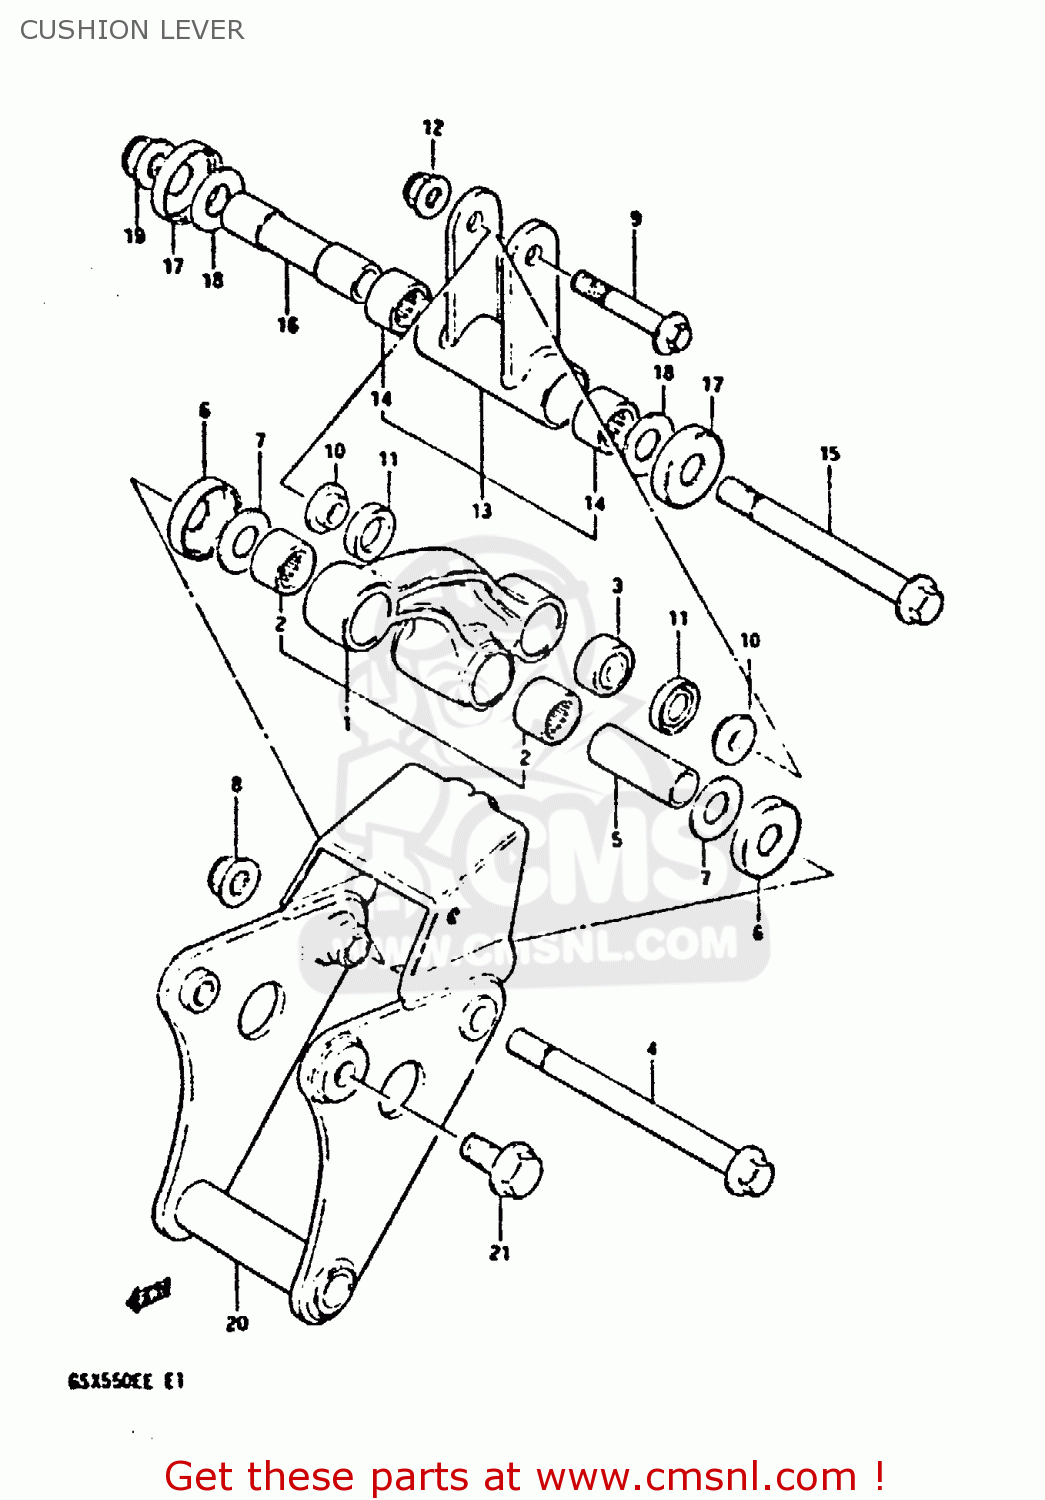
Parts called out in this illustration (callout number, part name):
1	LEVER SET,REAR CUSHION
2	ROLLER BEARING (17X24X2
3	BEARING(10X24X15)
4	SHAFT,REAR CUSHION LEVER
5	SPACER,REAR CUSHION LEVER
6	COVER,RR SWGARM DUST SEAL
7	WASHER
8	NUT 12MM
9	BOLT(10X52)
10	SPACER
11	DUST SEAL,RR CUSHION LEVER RR
12	NUT
13	LEVER SET,REAR CUSHION
14	ROLLER BEARING (17X24X2
15	BOLT,REAR CUSHION ROD
16	SPACER,REAR CUSHION ROD
17	COVER,RR SWGARM DUST SEAL
18	WASHER
19	NUT 12MM
20	HOLDER
21	BOLT(12X23)
